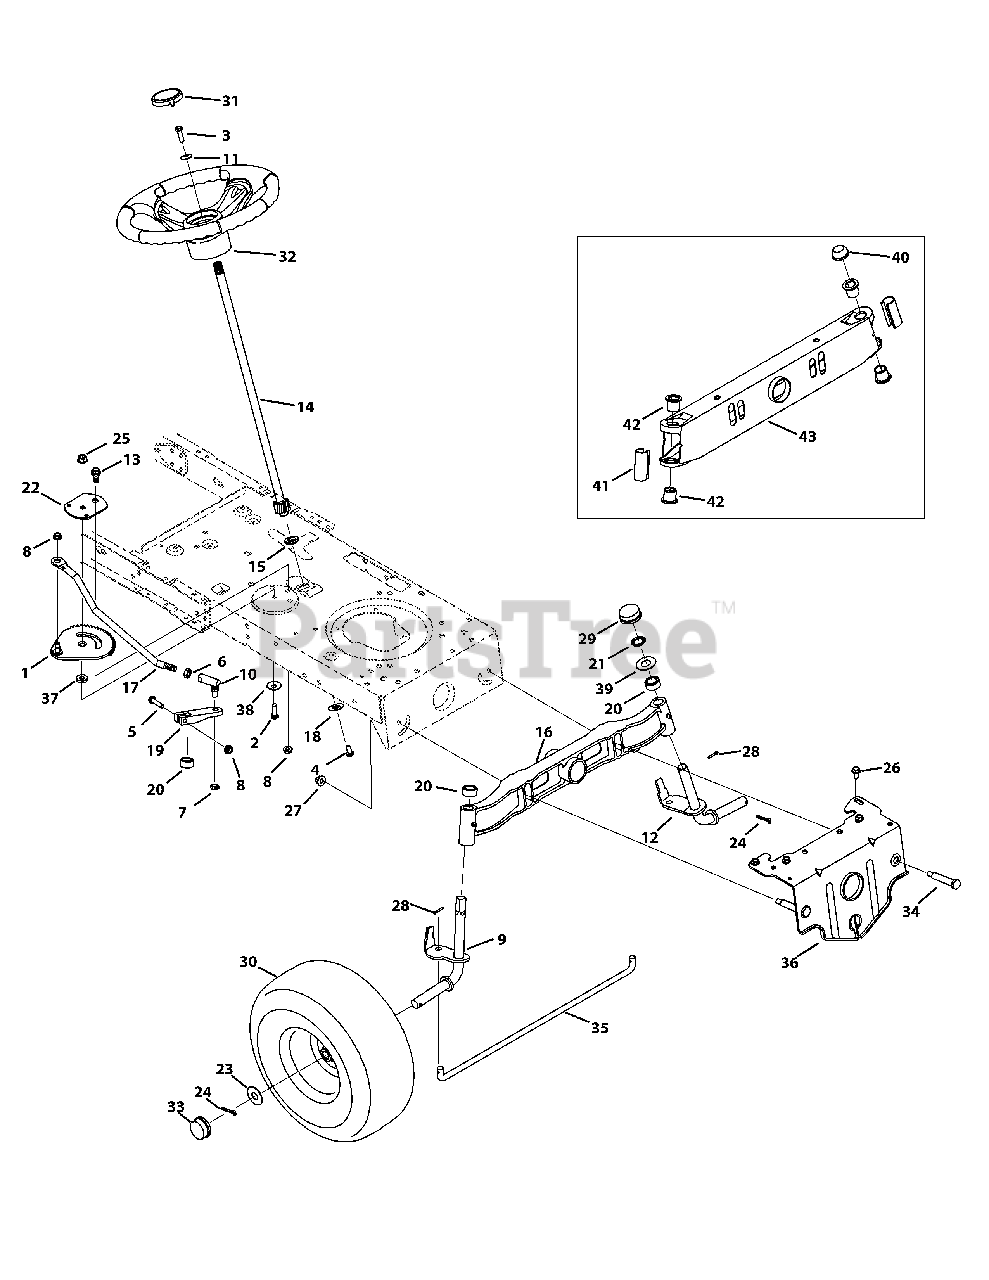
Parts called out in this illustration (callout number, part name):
1	Front Steering Gear Assembly
2	Hex Screw, 3/8-16 x 1.00
3	Hex Screw, 5/16-18 x 1.00, Lock
4	Machine Screw, 5/16-18 x .750
5	Hex Screw, 5/16-18 x 1.75
6	Jam Nut, 7/16-20
7	Jamlock Nut, 3/8-24
8	Flangelock Nut, 5/16-18
9	Front RH Axle
10	Ball Joint, 7/16-20
11	Bell Washer, .340 x .872 x .060
12	Front LH Axle
13	Shoulder Bolt, 5/16-18 x .435 x .350
14	Steering Shaft, 5/8
15	Flange Bearing, 5/8
16	Pivot Bar, Cast
17	Steering Link
18	Cap, 1.25 x .16
19	Steering Block
20	Spacer, .71 x .125 x .56
21	Push Nut 3/4 Dia.
22	Stabilizer Plate
23	Flat Washer, .781 x 1.590
24	Cotter Pin, 5/32 x 1.25
25	Flangelock Nut, 3/8-16
26	Screw, 5/16-18 x .750
27	Flangelock Nut, 3/8-16
28	Cotter Pin, .125 x .75
29	Push Cap, Cast
30	Wheel Assembly
31	Sprig Cap
31	No Sprig Cap
32	Steering Wheel
33	Hub Cap
34	Shoulder Bolt, 3/8-16 x .500 x 2.38
35	Fixed Rod
36	Pivot Bar Bracket
37	Spacer, .38 ID x .854 OD x .20
38	Bell Washer, .390 x 1.13 x .062
39	Washer, Flat, .78 x 1.59 x .60
40	Push Cap, 3/4
41	Standard Axle Cap
42	Flange Bearing, .760 x .941 x 1.0
43	Pivot Axle
